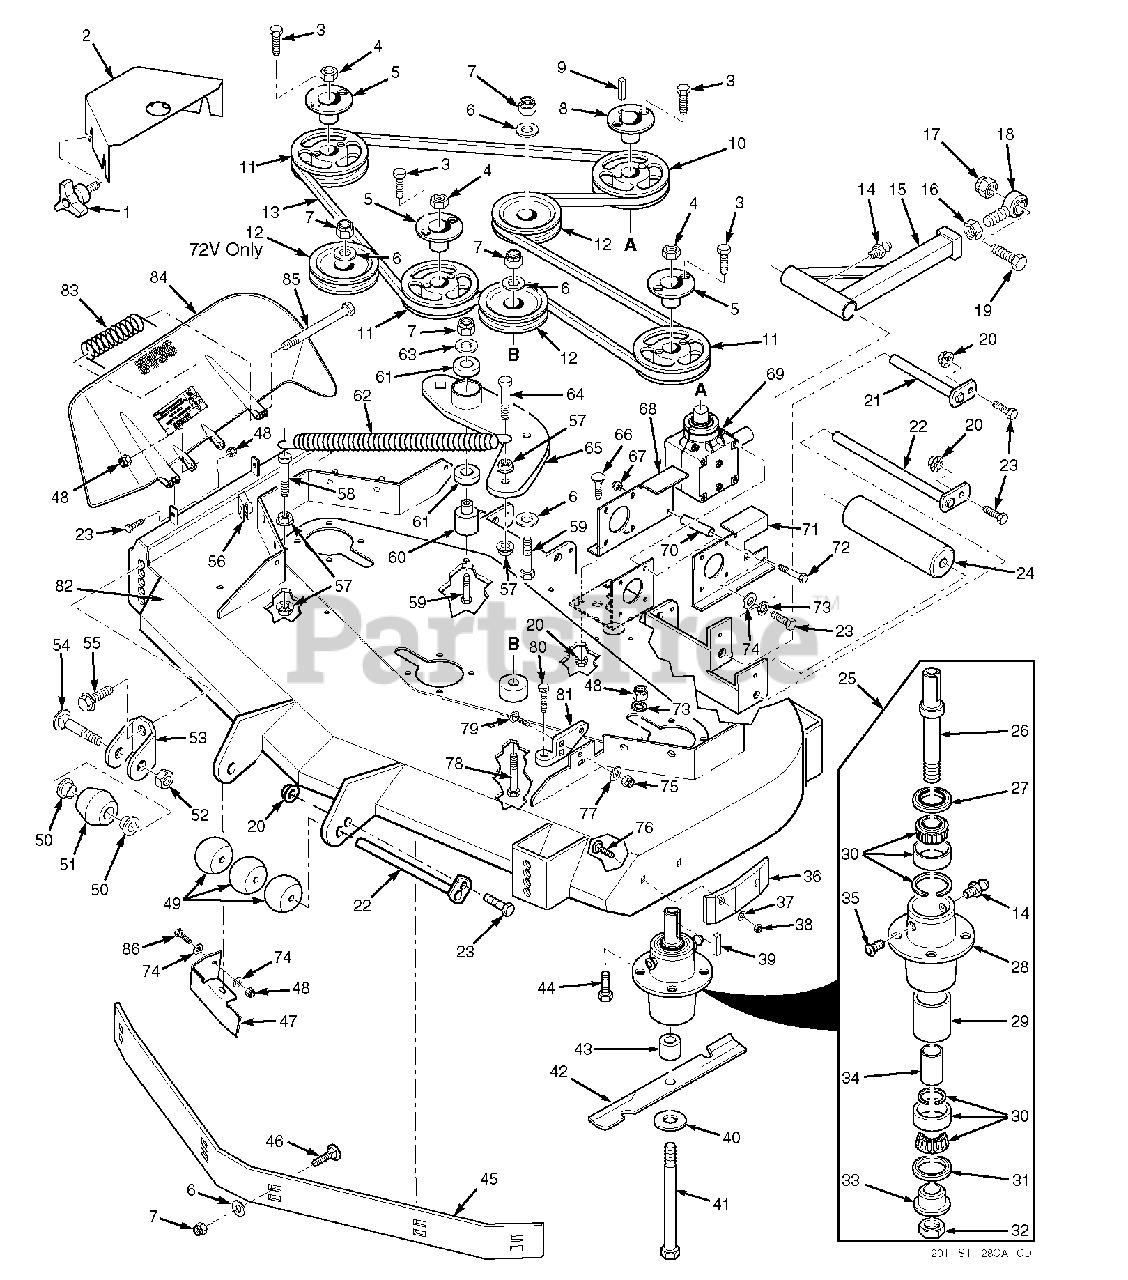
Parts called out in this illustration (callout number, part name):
1	Wing Nut, 3/8-16
2	Belt Cover
2	Belt Cover RH
2	Belt Cover LH
3	Bolt, Hex Head 1/4-20 x 1" Grd 8
4	Nut, 5/8-11 UNC
5	Tapered Hub, 1-1/8" Bore
6	Flatwasher, 3/8" (.391 x .938 x .105)
7	Nut, Hex Elastic Stop 3/8-16
8	Tapered Hub, 1" Bore
9	Key, 1/4 x 1/4 x 1-1/4"
10	Pulley, 6.75 O.D.
10	Pulley, 6.95 O.D.
11	Pulley, 5.75 O.D.
11	Pulley, 6.75 O.D.
12	Pulley, Idler
13	Belt, Cutter Deck Drive
14	Grease Fitting
15	Pusharm
16	Nut, Hex Head 5/8-18 UNF
17	Nut, Hex Elastic Stop 5/8-11
18	Rod End, 5/8" Male RH Thread
19	Bolt, Hex Head 5/8-11 x 4-1/2"
20	Nut, Hex Serrated Flange 5/16-18
21	Push Arm Shaft
22	Roller Shaft
23	Bolt, Hex Head 5/16-18 x 1-3/4"
24	Wheel, Anti-Scalp
25	Spindle Assembly
26	Spindle Shaft
27	Seal, Top
28	Spindle Housing
29	Spacer, Outside
30	Bearing Assembly
31	Seal, Bottom
32	Nut, Special 1-1/16-18
33	Spindle Bushing, Bottom
34	Spacer, Inside
35	Relief Fitting, Tapered Spindle
36	Wear Pad
37	Flatwasher, 5/16"
38	Nut, Center Lock 5/16-18
39	Key, 1/4 x 1/4 x 2"
40	Flatwasher, 5/8" Hardened
41	Bolt, Hex Head 5/8-11 x 9-1/2"
42	Cutter Blade, 21"
42	Cutter Blade, 24.5"
43	Spacer, Spindle Bottom
44	Bolt, Hex Head 5/16-18 x 1-3/4"
45	Baffle, Custom Cut 61V
45	Baffle, Custom Cut 72V
46	Bolt, Carriage 3/8-16 x 1"
47	Discharge Baffle 61V
47	Discharge Baffle 72V
48	Nut, Hex Elastic Stop 5/16-18 Grd 8
49	Wheel, Anti-Scalp
50	Bushing, .376 I.D. Oilite
51	Anti-Scalp Wheel
52	Locknut, 3/8-16 Center Lock
53	Anti-Scalp Wheel Bracket
54	Bolt, Carriage 3/8-16 x 4"
55	Bolt, Hex Serrated Flange 3/8-16 x 1"
56	U-Nut, 3/8-16
57	Nut, Hex Serrated Flange 3/8-16
58	Bolt, Hex Head 3/8-16 x 1-1/2"
59	Bolt, Hex Head 3/8-16 x 3"
60	Pivot, Idler - Short
61	Bearings, Ball
62	Spring, Cutter Deck
63	Flatwasher,3/8-.39 x .938 x .105 HD
64	Bolt, Hex Head 3/8-16 x 1-1/2" Grd 8
65	Idler Arm, Cutter Deck
66	Bolt, Carriage 5/16-18 x 3/4"
67	Nut, Elastic Stop 5/16-18
68	Mounting Plate, RH Gearbox
69	Gearbox Assembly, Deck Drive
70	Spacer, Gearbox Mount
71	Mounting Plate, LH Gearbox
72	Bolt, Hex Head 5/16-18 x 4-3/4"
73	Lockwasher, 5/16"
74	Flatwasher, 5/16" (.375 x .875 x .083)
75	Nut, Elastic Stop 7/16-14
76	Bolt, Carraige 5/16-18 x 3/4"
77	Flatwasher, 7/16-.500 x 1.25 x .083
78	Bolt, Hex Head 3/8-16 x 3-1/4"
79	Bolt, Carriage 7/16-14 x 1-1/4"
80	Bolt, Deck Adjust
81	Lever Assy, Deck Level
82	Cutter Deck 61 V w/Decals
82	Cutter Deck 72 V w/Decals
83	Spring, Discharge Chute
84	Discharge Chute 61V
84	Discharge Chute 72V
85	Bolt, Hex Head 5/16-18 x 4-1/2"
86	Bolt, Hex Head 5/16-18 x 1"
